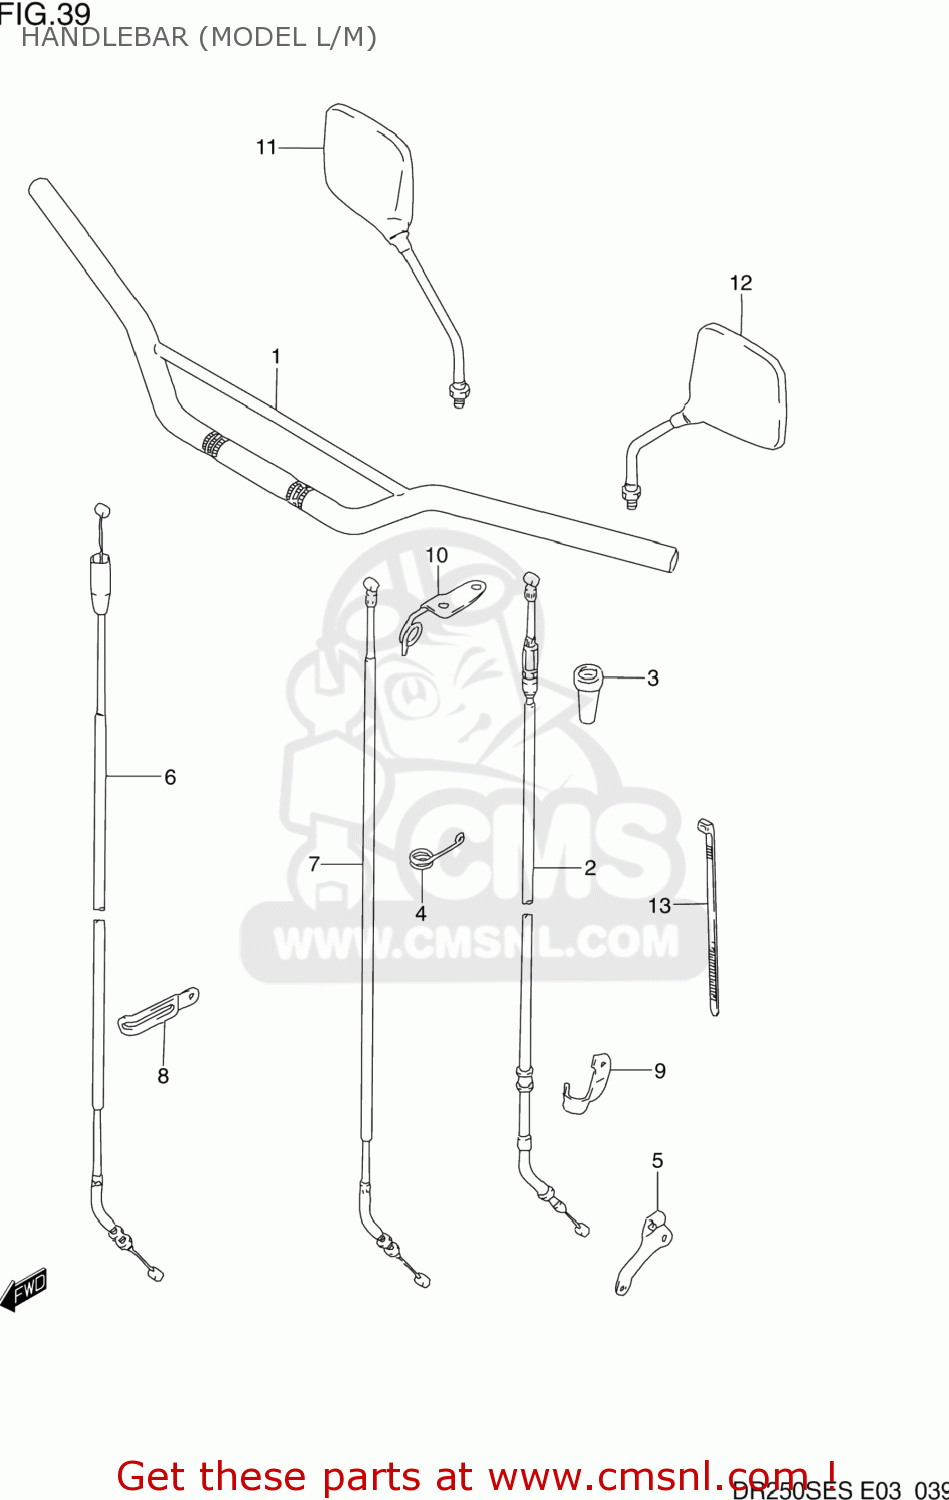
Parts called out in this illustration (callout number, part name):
1	HANDLEBAR
2	CABLE ASSEMBLY,CLUTCH
3	BOOT,CLUTCH CABLE
4	GUIDE,CLUTCH CABLE
5	STOPPER,CLUTCH CABLE
6	CABLE ASSY,THROTTLE
7	CABLE ASSY DECOMP
8	CLAMP
9	CLAMP,CLUTCH CABLE
10	GUIDE,CABLE
11	MIRROR ASSEMBLY,REAR VIEW
12	MIRROR ASSEMBLY,LEFT
13	CLAMP(L:100)
